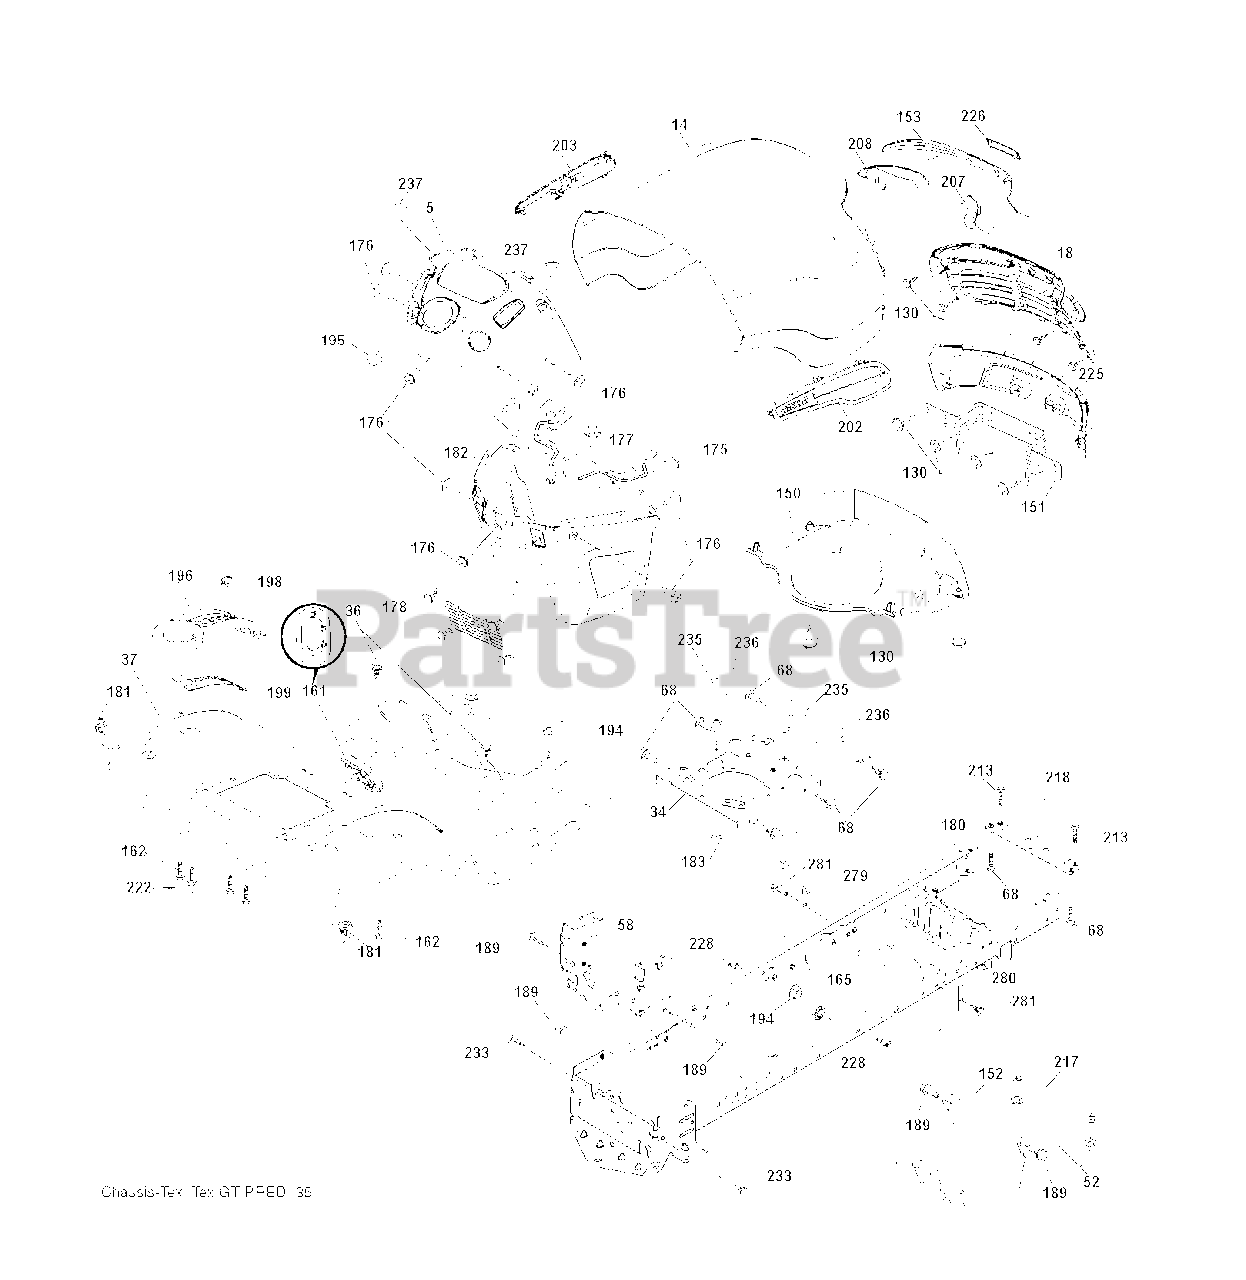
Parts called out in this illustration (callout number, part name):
34	PLATE.ENGINE.WELDED.CHASSIS
36	SCREW 5/16"
52	LOCKNUT
58	DRAWBAR.UPPER.2PC,LRG.FENDER
130	SCREW.#10 X 0.750.BOS THREAD
152	SHIELD BROWNING
161	CONSOLE.FUEL.WINDOW.STGT.BLACK
162	SCREW.HI-LO.CONSOLE
165	SUPPORT.TANK.REAR.W/TE
175	PLATE.CROSSMEMBER.HUSQ
176	SCREW.#10-24X5/8.RN.QU
177	BUSHING,STEERING
178	CARGO.ASM.NET.TXGT.W/C
180	CHASS.WLDMNT.TL.12GA/2P.48/54
181	FEND/FTRST.PCH.CPH.NFW
182	DASH.LOWER.COMMON.12V.ADAPTOR
183	BOLT.5/16-18X1-1/4 FULL.THREAD
189	SCREW
194	NUT LOCK HEX FLANGE 5/16-18
195	PLUG.HOLE.DASH.LOWER.12V.BLK
198	INDICATOR DECK LIFT
199	PLATE DECK LIFT
213	BOLT
217	ROD.PIVOT.HOOD
218	X-PIECE.HOOD.STOP.NON/
222	SCREW.1/4-20X5/8
228	STUD.FASTNER.W/ANTI-ROTATE
233	BOLT.SHOULDER
235	SPACER FENDER
236	NUT.CENTERLOCK.5/16-
237	PLUG.MOUNT.CARGO.BLK
278	BRKT.HOOD/MUFF.STEALTH
279	ROD UPSTOP
280	ROD UPSTOP
281	SCREW 3/8-16X1
